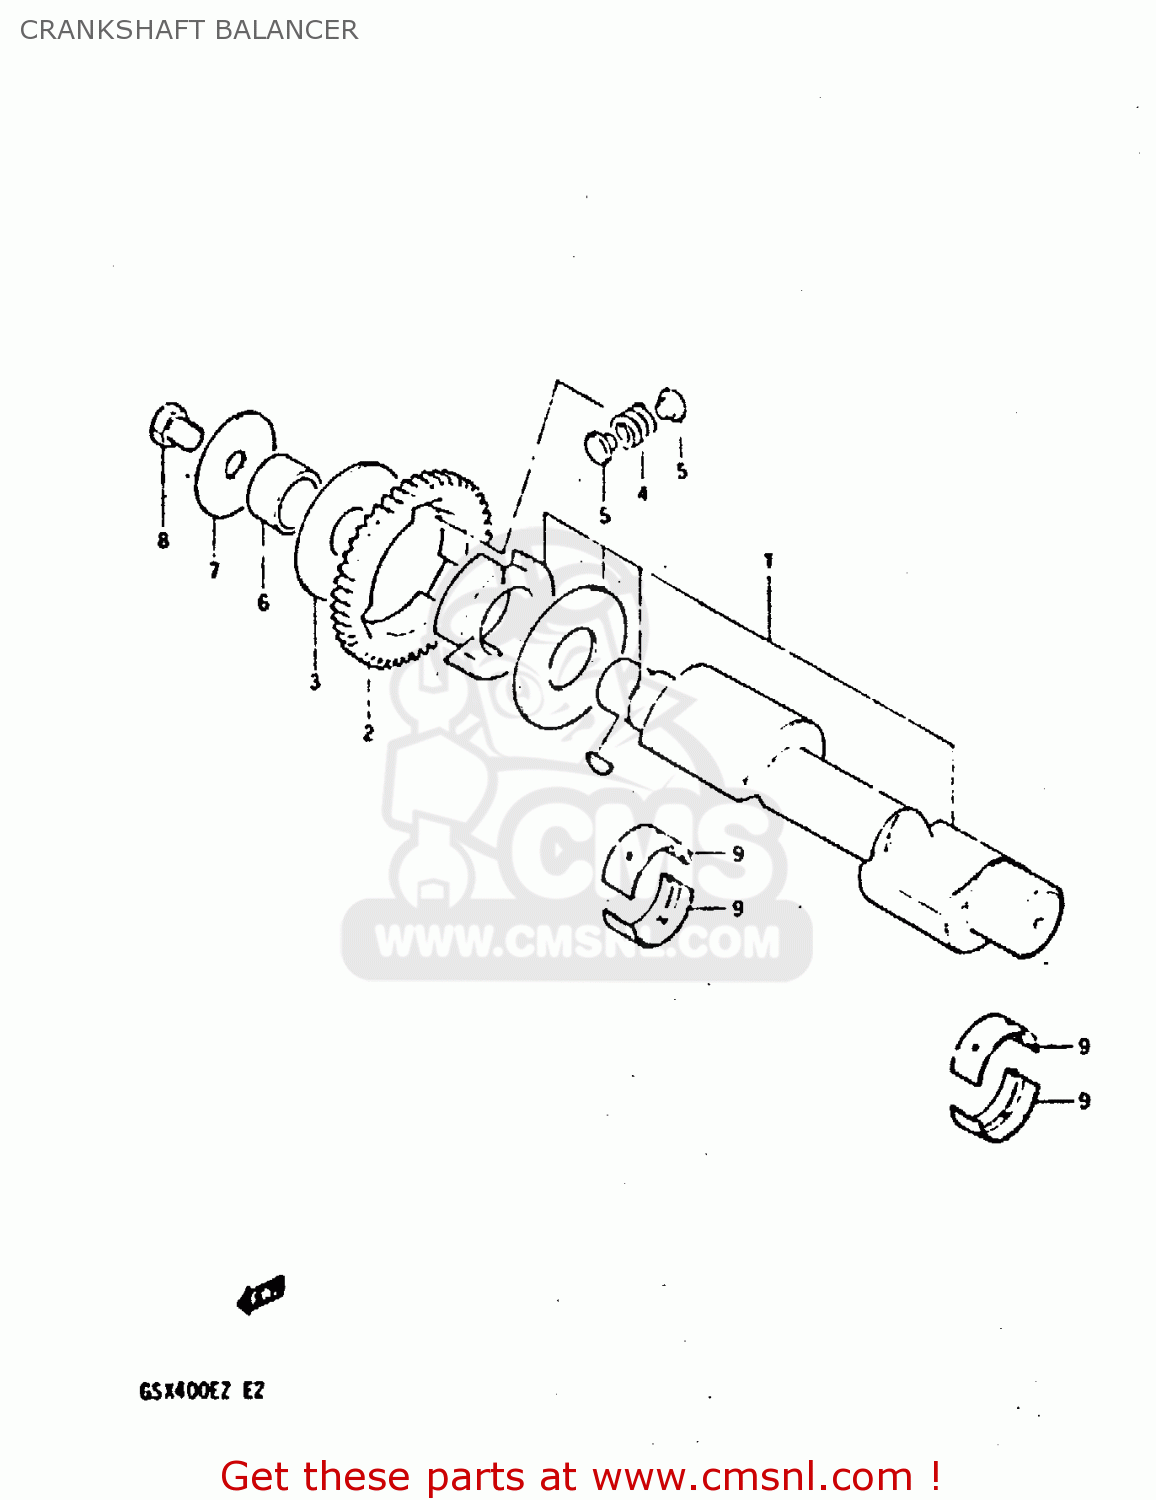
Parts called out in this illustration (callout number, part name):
1	BALANCER,CRANKSHAFT
2	GEAR,CRANK BALANCER DRIVE
3	WASHER
4	SPRING
5	PIN
6	SPACER
7	WASHER(12X50X3)
8	BOLT
9	METAL CRANKSHAFT
